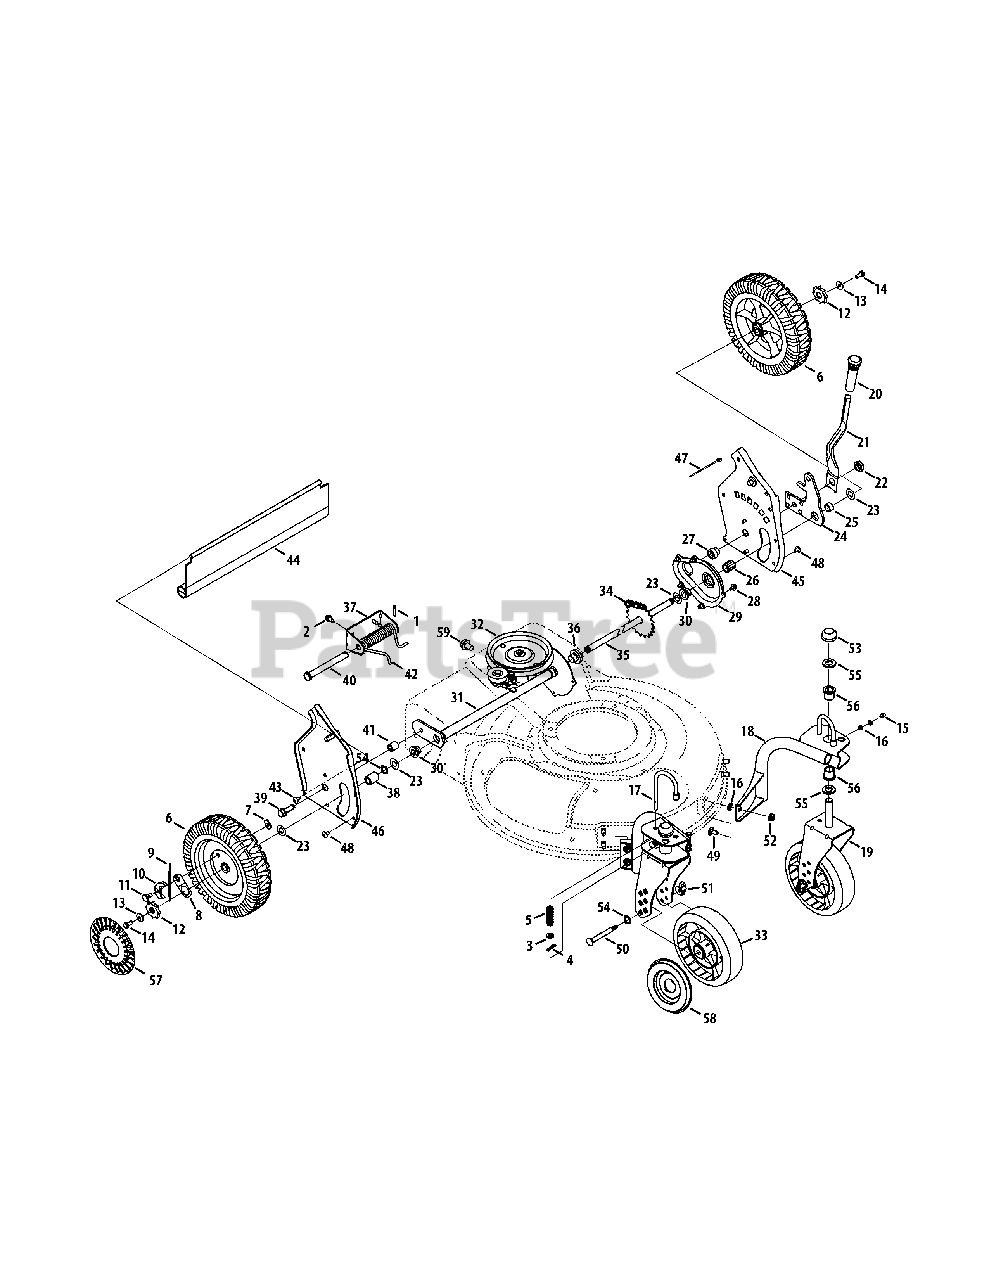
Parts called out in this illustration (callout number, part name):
1	Cotter Pin
2	Screw 1/4-14 x .825
3	Flat Washer.330 ID x.630 OD
4	Cotter Pin
5	Compression Spring
6	Wheel, 9 x 2.125
7	Top Lock Tab Weld Nut 1/4-20
8	Ratchet Pawl Plate
9	Plastic Spring Ratchet
10	Pawl RH
10	Pawl LH
11	Shlder Screw.340 ID x.285 OD
12	Wheel Ratchet
13	Bell Washer.265 ID x.75 OD
14	Hex Cap Screw 1/4-20 x.620
15	Grease Fitting
16	Push Nut
17	Wheel Pin Lock
18	Caster Assembly RH
18	Caster Assembly LH
19	Caster Bracket Assembly RH
19	Caster Bracket Assembly LH
21	Spring Lever
22	Shoulder Nut.825 x .165 Lg.
23	Flat Washer .508 ID x 1.0 OD
24	Pivot Arm Assembly
25	Spacer .510 ID x .70 OD
26	Slv Bearing .504 ID x .830 OD
27	Shlder Spacer, .385ID x .715Lg
28	Tap Screw 1/4-20 x .375
29	Chain Cover Assembly
30	Flge Bearing .506 ID x .590 Lg
31	Transmission Axle Assembly
32	Transmission Ass’y Complete
33	Wheel 7 x 2
34	Chain
35	Rear Axle Assembly
36	Flge Bearing .506 ID x .715 Lg
37	Height Adjustment Spring Brkt.
38	Spacer .550 ID x .750 OD
39	Screw 3/8-16 x .25
40	Clevis Pin .50 Dia x 4.82 Lg.
41	Spacer .385 ID x .624 OD
42	Torsion Spring
43	Screw, AB, #10-16 x .500
44	Trail Shield
45	Handle Bracket Assembly - LH
46	Handle Bracket Assembly - RH
47	Cable Tie
48	Screw 1/4-14 x.500
49	Carriage Bolt 5/16-18 x.62
50	Caster Axle
51	Wing Nut
52	Flange Lock Nut 5/16-18
53	Push Cap
54	Wave Washer, .510 x .750 x .017
55	Flat Washer.640 ID x 1.12 OD
56	Flange Bearing
57	Hubcap - Radial Spoke
58	Hubcap - Spoke w/ Hole
59	Screw, 5/16-18 x .625
